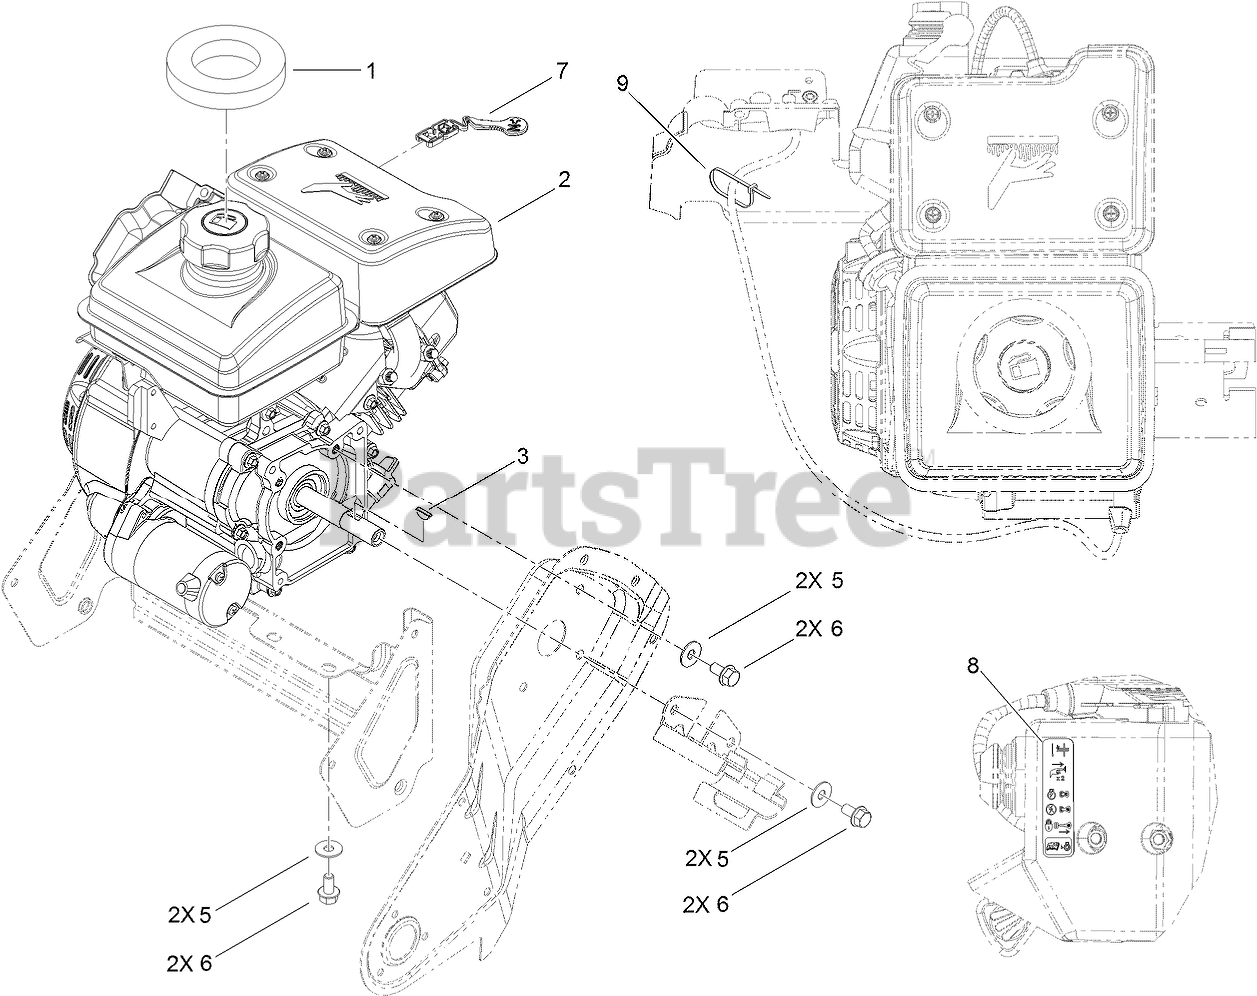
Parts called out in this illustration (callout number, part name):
1	SEAL-TANK
2	ENGINE-LC154FDS-1
3	KEY-WOODRUFF
5	WASHER-BELLEVILLE
6	SCREW-HH
7	LEVER-CHOKE
8	DECAL-CONTROLS, ENGINE
9	TIE-CABLE
